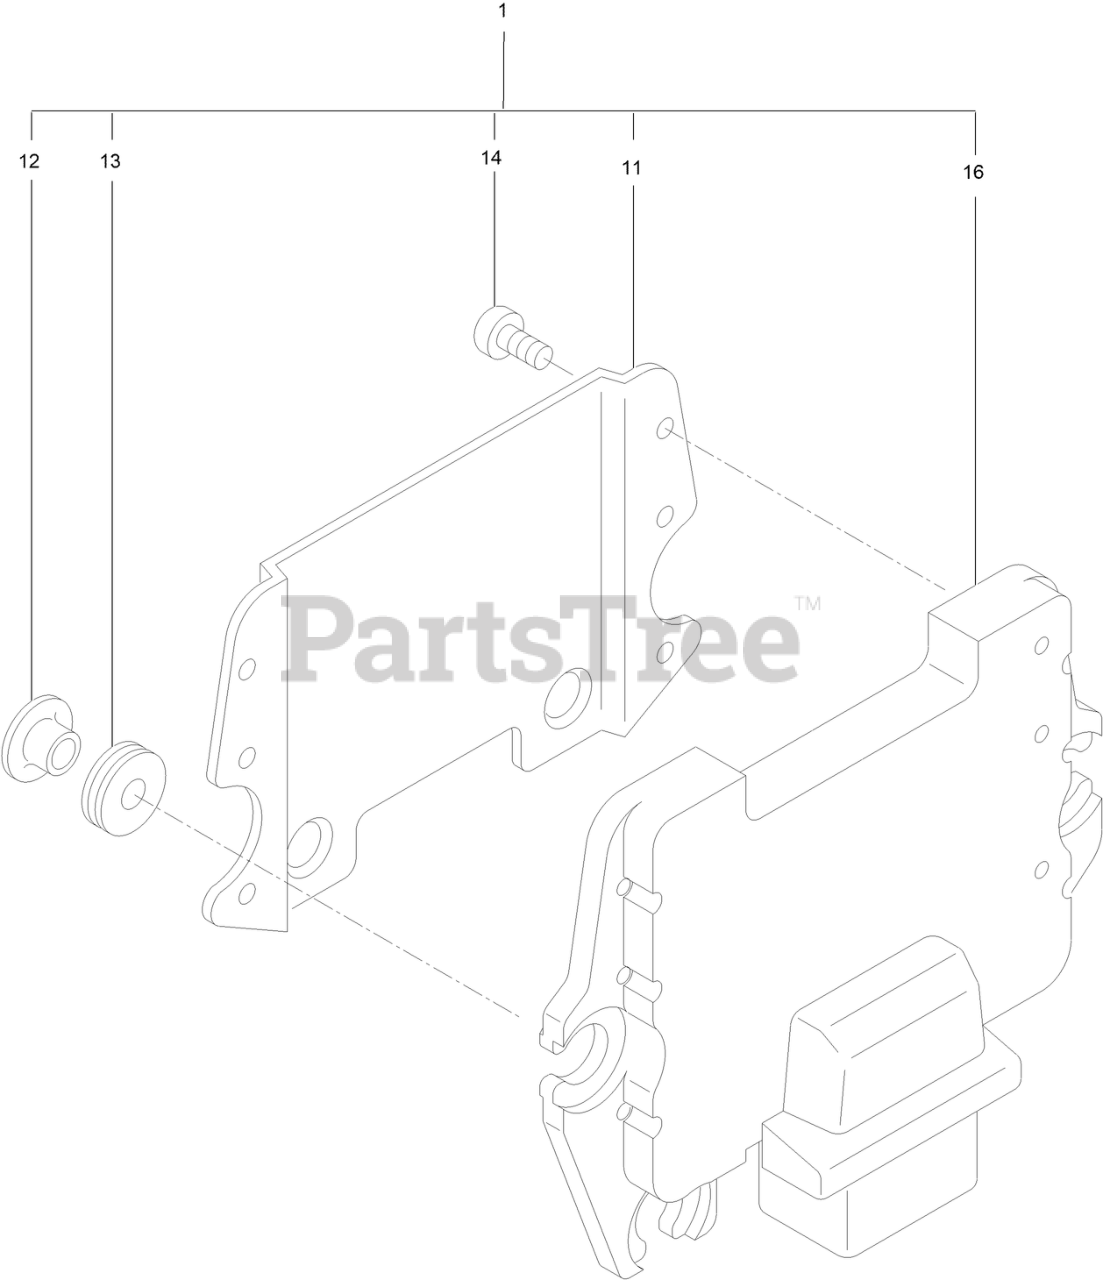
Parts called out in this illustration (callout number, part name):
1	ECU ASM
11	SHIELD
12	COLLAR
13	ABSORBER
16	ECU ASM-SERVICE
